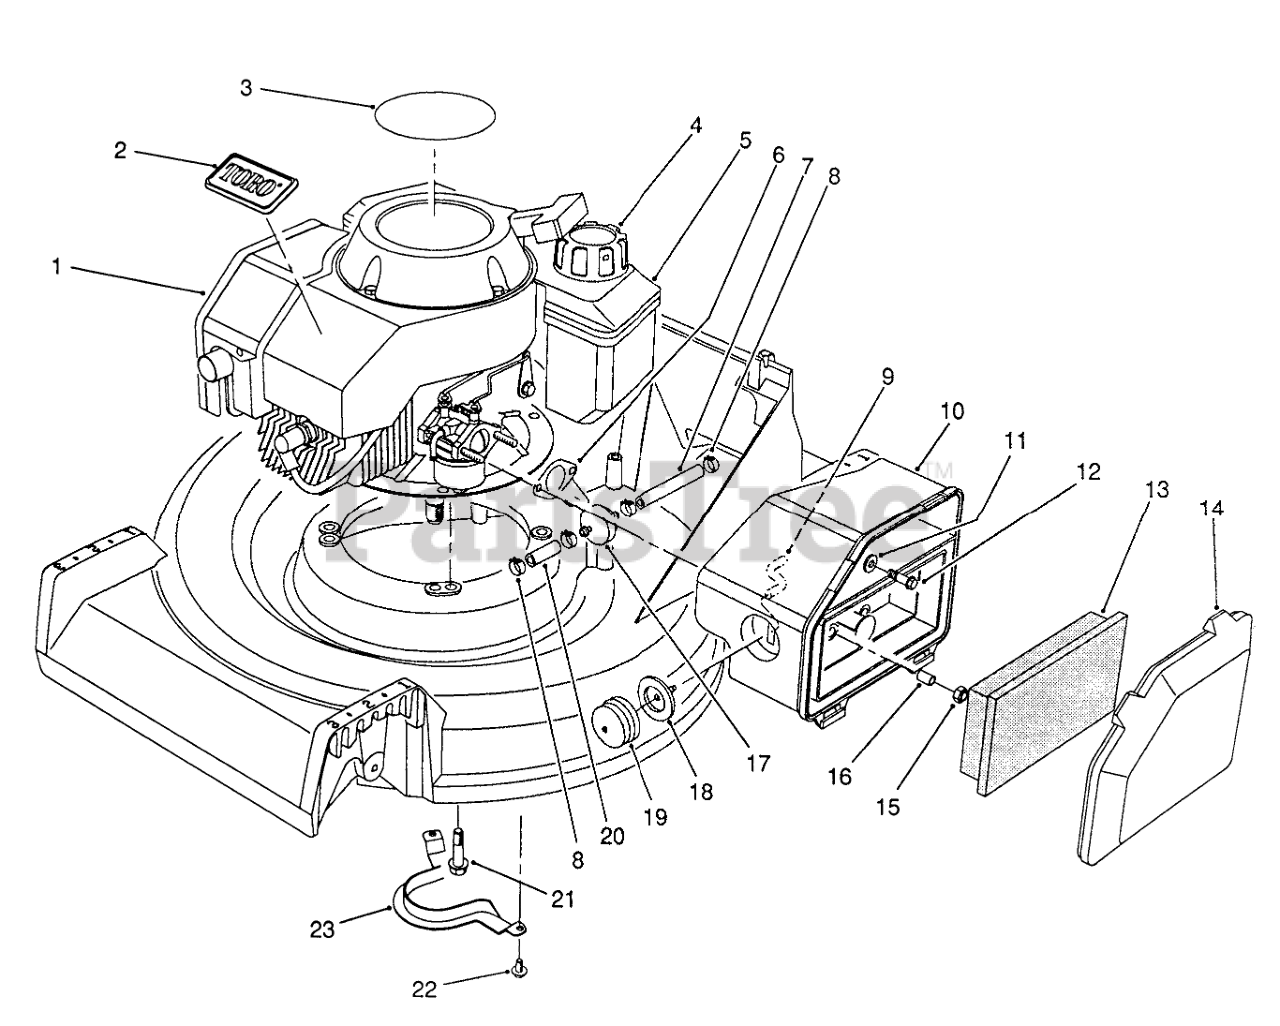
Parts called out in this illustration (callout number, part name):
1	Engine-2 Cycle
2	TORO LOGO PLT
3	DECAL- 2 CYC RECOIL
4	GAS CAP ASM
5	FUEL TANK ASM
6	GASKET-AIR CLEANER
7	HOSE-FUEL
8	CLAMP-FUEL LINE
9	HOSE-PRIMER
10	BODY-AIR CLEANER
11	WASHER-FLAT
12	SCREW-HH
13	ELEMENT-AIR CLEANER
14	COVER-AIR CLEANER
16	SPACER
17	FILTER-FUEL
18	BODY-PRIMER
19	BULB-PRIMER
20	HOSE-FUEL
21	SCREW-HHF
22	SCREW-HWHTF
23	Guide-Belt
